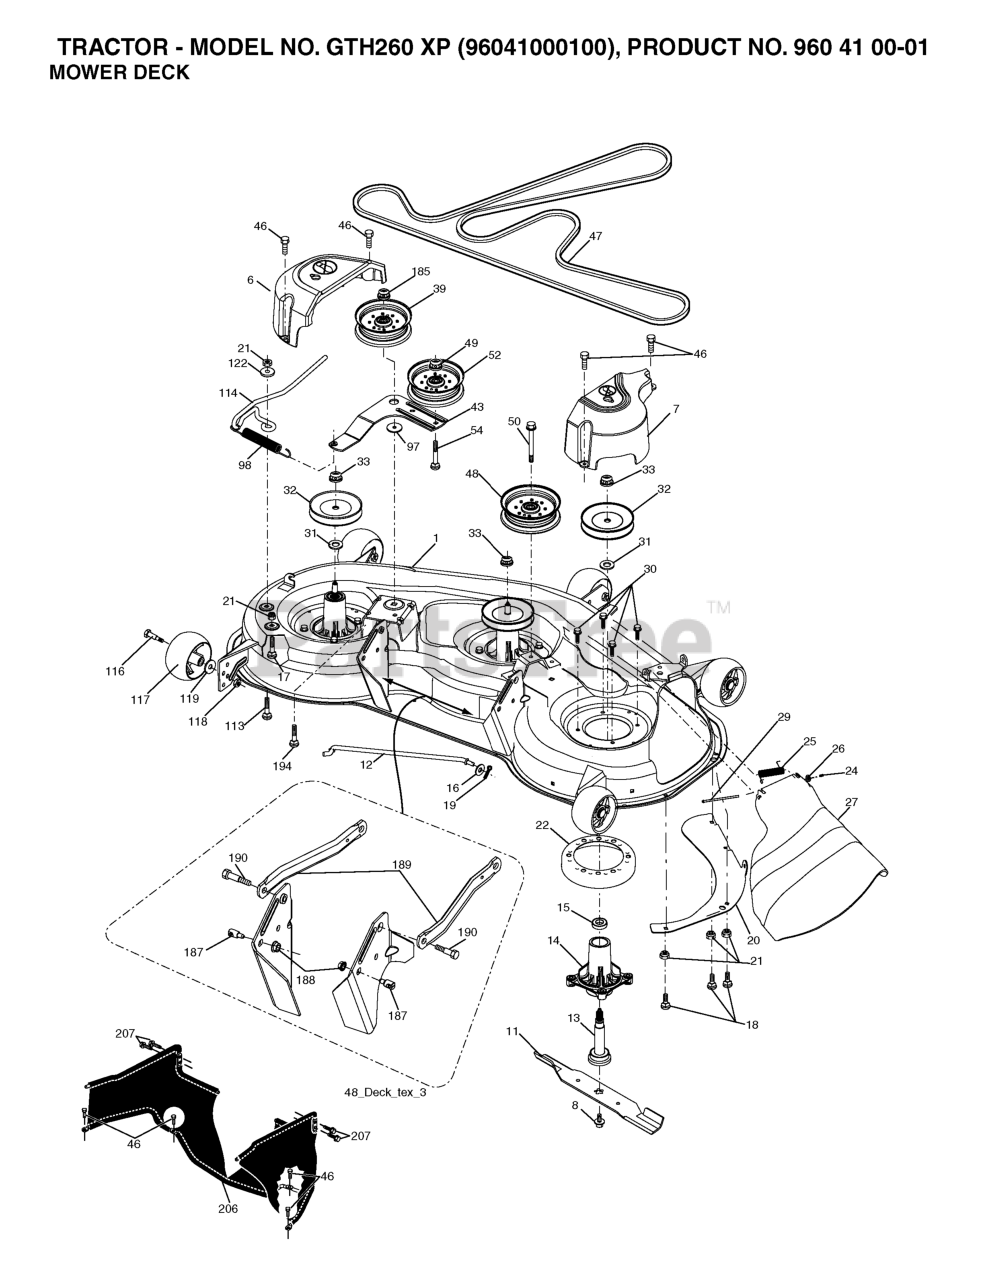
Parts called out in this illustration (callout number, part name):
1	DECK.WELDMENT.48"2006
8	BOLT 7/16 ASM BLADE
11	48" HI-LIFT BLADE
12	ROD.ANTI.SWAY.48/54"TE
13	SHAFT ASM MANDREL
14	RP.HOUSING.MANDREL.4PT.
16	WASHER
17	BOLT.CARR.5/16-18X5/8.SHORT
18	BOLT
19	PIN.COTTER.5/16.BOW TI
20	BAFFLE, VORTEX MWR
21	LOCKNUT
22	STRIPPER.MANDREL.ROUND.BLACK
24	CAP-SLEEVE LT
25	SPRING, TORSION
26	NUT PUSH M
27	DEFLECTOR SUBS TO 532 180655
29	ROD.HINGE
30	SCREW, WASHER HEAD
31	WASHER.SPACER.MANDREL
32	PULLEY MANDREL
33	NUT.FLANGE.LOCK.TOP
39	RB PULLEY.IDLER.4.50/HUB SPEC
46	SCREW.1/4-20X5/8
47	BELT.DRIVE.DECK
48	PULLEY.IDLER.48"PRIMARY
49	NUT LOCK FLG 3/8-16 UNC
50	BOLT.3/8-16X1.50
52	PULLEY.IDLER.2006
54	SCREW TT 3/8-16X2-1/4 UNC
98	SPRING, DECK DRIVE
114	ROD.TENSION.RELIEF.TEX (2 2)
116	BOLT.SHOULDER.3/8-16X3-5/8.
117	RP WHEEL. GUAGE RALLY
120	WASHER
122	BUSHING.RELIEF.TENSION
185	NUT.LOCK.FLANGE.7/16
187	STUD.FASTNER.W/ANTI-ROTATE
188	LOCKNUT-FLANGE 5/16-18
189	ARM.SUSPENSION.MOWER
190	BOLT.SHOULDER
194	BOLT.CARR.SQNK.7/16
205	NUT.CROWNLOCK.1/4
207	SCREW
